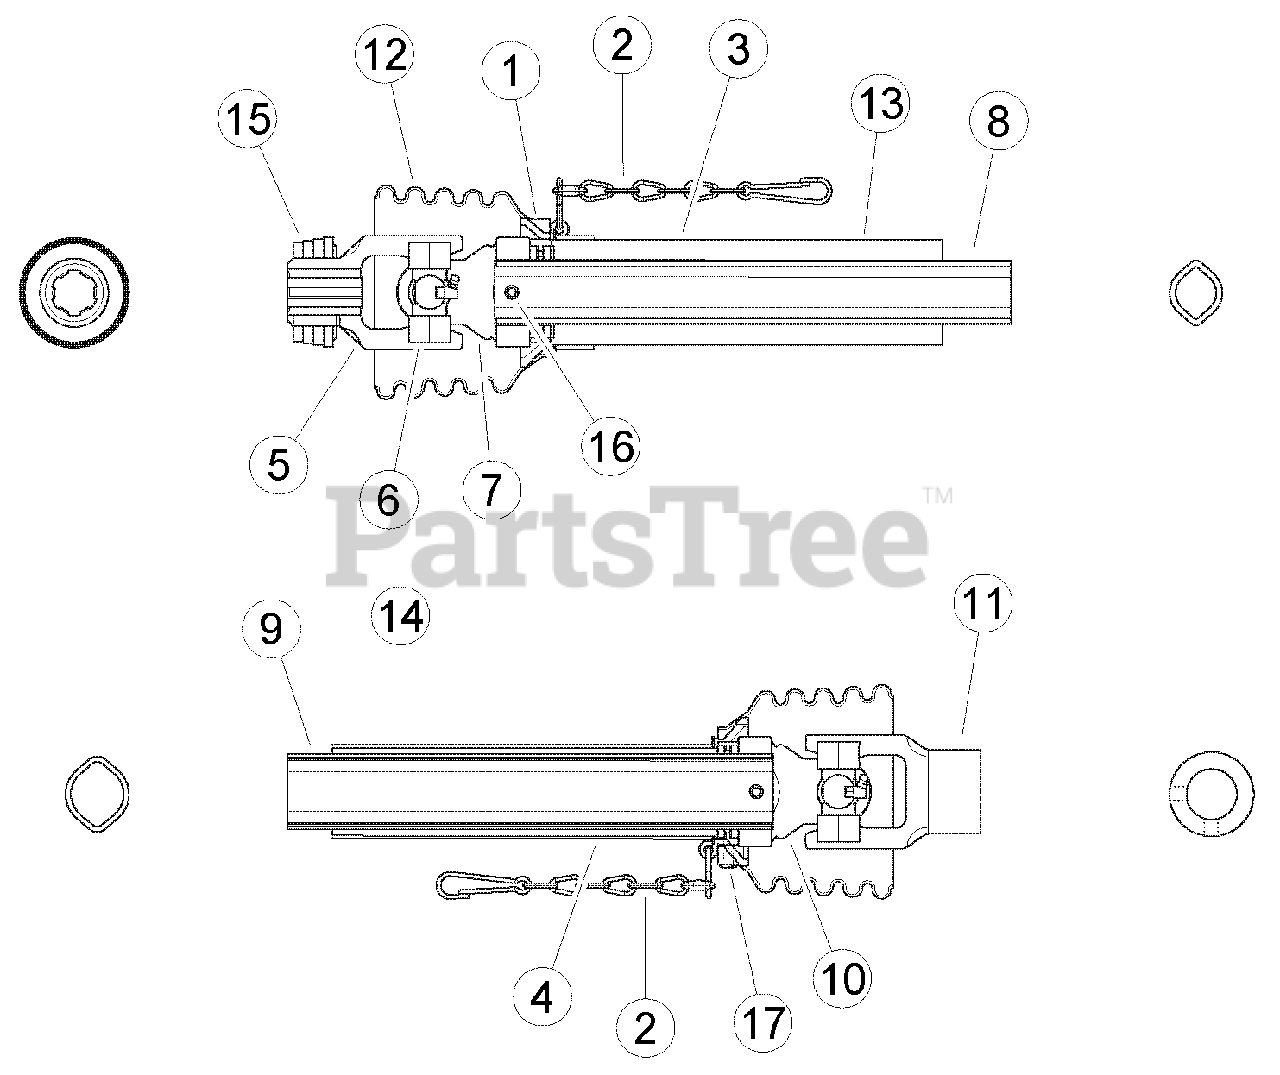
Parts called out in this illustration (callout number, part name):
1	BEARING, RING SC15
2	SAFETY CHAIN
3	DECAL, OUT
4	DECAL, IN
5	YOKE, 3/8 - 6 SPL. ASGE
6	CROSS & BEARING KIT
7	YOKE, INBOARD OV
8	INNER PROFILE OV
9	OUTER PROFILE I
10	YOKE, INBOARD I
12	SHIELD, CONE 4 RIB
13	SHIELD, OUTER TUBE OVL.
14	SHIELD, INNER TUBE RND
15	KIT, RETAINING RING / TRACTOR SIDE
16	PIN, SPRING 10 X 65
